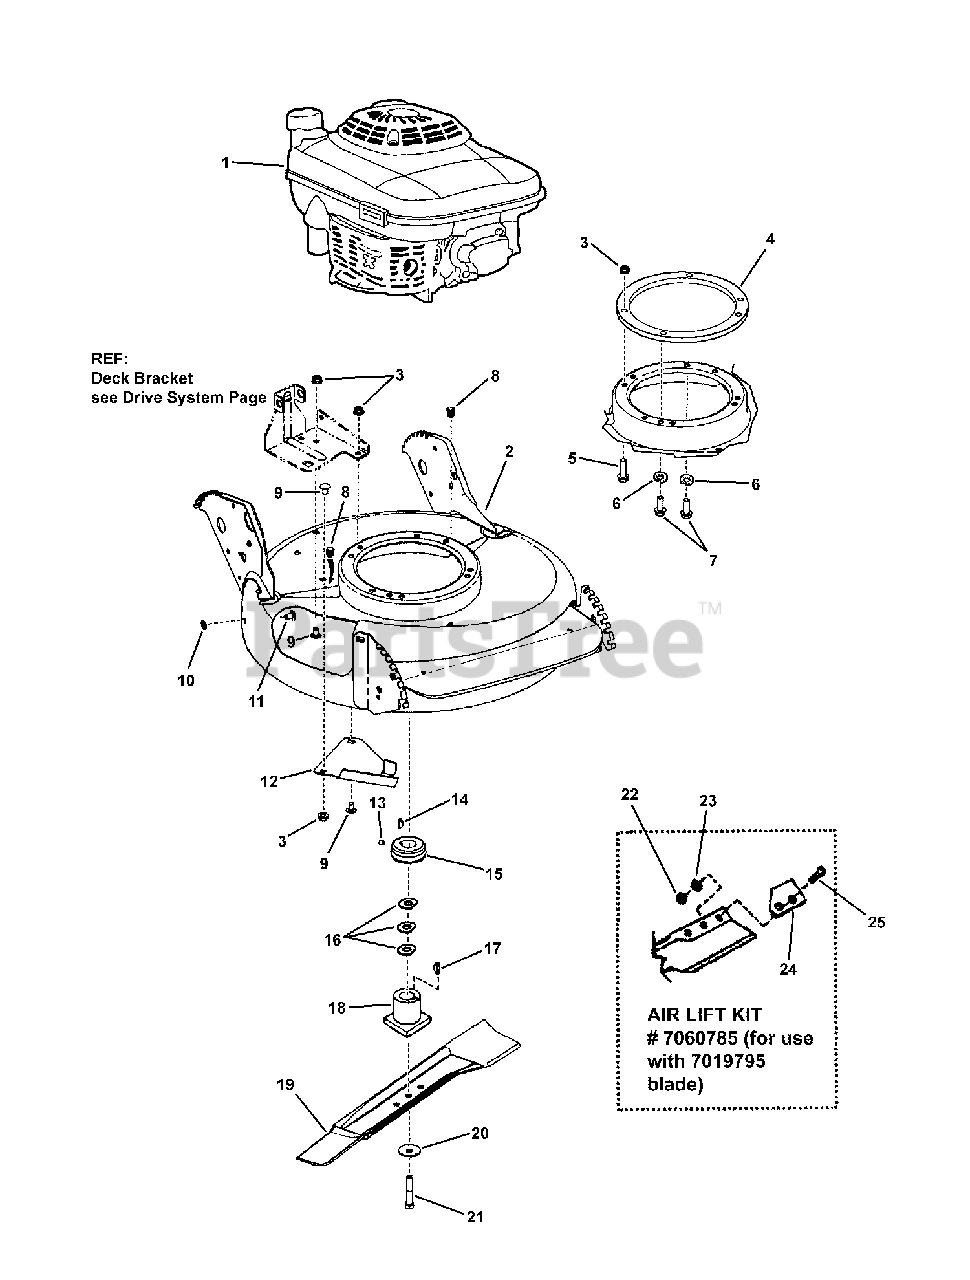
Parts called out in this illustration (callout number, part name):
1	* ENGINE, 6 TP Kawasaki w/side recoil
2	WELDMENT, Deck, 21", Self-Propelled, Hi-Vac
3	NUT, 5/16-18 Hex Flange Lock, GR 5
4	RING, Engine Spacer
5	BOLT, 5/16-18 x 1-1/2" Hex Flange Lock, GR5
5	SCREW, 3/8-16 X1, Hex Washer Self-Tap, BZ
6	WASHER, .32 x .58 x .08 Split Lock
7	SCREW, 5/16-24 x 1-1/4" Hex Head Cap GR 5
8	PLUG, Hole, Polyethylene
9	BOLT, 5/16-18 x 1/2", Short Neck Carriage, GR 5
10	RETAINER, 5/16" Bolt
11	BOLT, 5/16-18 x 3/4" Short Neck Carriage GR 5
12	COVER, Belt
13	SET SCREW, 5/16-18 x 1/2" Hex Socket Head
14	KEY, Woodruff #HP-506 Hi-Pro
15	PULLEY- Engine (25mm I.D. x 2-1/8" O.D.)
15	PULLEY- Engine (1.085 I.D. x 2-1/8" O.D.)
16	SPACER, .06 Blade Hub
17	KEY, #505 Hi-Pro
18	** HUB, Blade Drive, 25mm I.D.
18	** HUB, Blade Drive, 7/8" I.D.
19	BLADE, Cutter (Standard Lift)
20	WASHER, Cone
21	SCREW, 3/8-24 x 2" Hex Head Cap, GR 5
22	NUT, 5/16-24 Hex, GR 5
23	WASHER, 5/16" Internal Tooth Lock
24	AIR LIFT
25	SCREW, 5/16-24 x 21/32" Oval Head Machine
